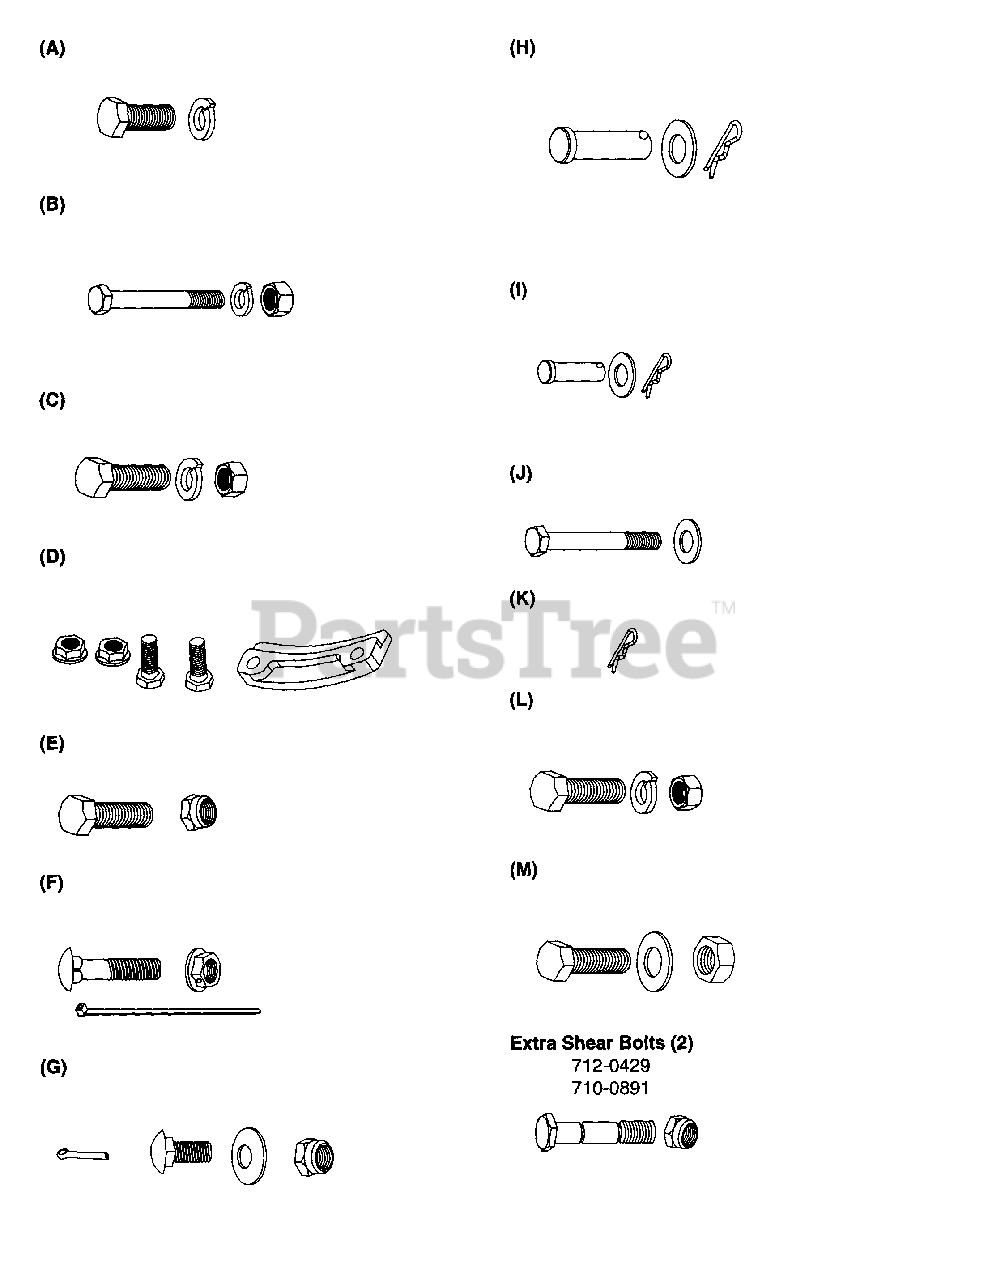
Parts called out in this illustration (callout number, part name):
710-0891	Shear Bolt
712-0429	Lock nut, Nylon 5/15-18 Thd.
A	Hex Bolts 3/8-16:1.00" Lg.
A	Lock washer 3/8 I.D.
B	Hex Cap Screw 1/2-13:4.00" Lg.
B	Lock Washer 1/2 I.D.
B	Hex Nut 1/2-13 Thd.
B	Bracket (Lift plate)
C	Hex Bolt 3/8-16 x 1" Lg.
C	Lock Washer 3/8 I.D.
C	Hex Nuts 3/8-16 Thd.
D	Chute Flange Keepers
D	Hex Bolt 1/4-20:.75" Lg.
D	Hex Flange Nut 1/4-20 Thd.
E	Hex Nut 3/8-16 Thd.
E	Hex Bolt 3/8-16: 1.50 Lg.
F	Carriage bolt 5/16-18: 1.5" Lg.
F	Hex Flg. Lock Nut 5/16-18 Thd.
F	Cable tie 3/16 x .05 x 7.4" Lg.
G	Cotter pin 3/32 x .75" Lg.
G	Carriage Bolt 5/16-18:.75 Lg.
G	Bell Washer .340 I.D x .872 O.D.
G	Lock Nut, Nylon 5/16-18 Thd.
H	Clevis pin 1/2 x 1.59" Lg.
H	Flat Washer 1/2 I.D.
H	Hair Pin .08 x 1.42" Lg.
I	Clevis Pin .50 Dia. x .78" Lg.
I	Flat Washer 1/2" I.D.
I	Hair Pin .08 x 1.42" Lg.
J	Hex Bolt 5/16-18:1.50" Lg.
J	Bell Washer .340 I.D. x .872 O.D.
K	Hair Pin .125 x 1.75 Lg.
L	Hex bolt 3/8-16: 1.00 Lg.
L	Lock washer 3/8 I.D.
L	Hex nut 3/8-16 Thd.
M	Hex Bolts 5/16-18:1.50 Lg.
M	Flat Washer .344 I.D.x 1.125 O.D.
M	Hex Nut 5/16-18 Thd.
